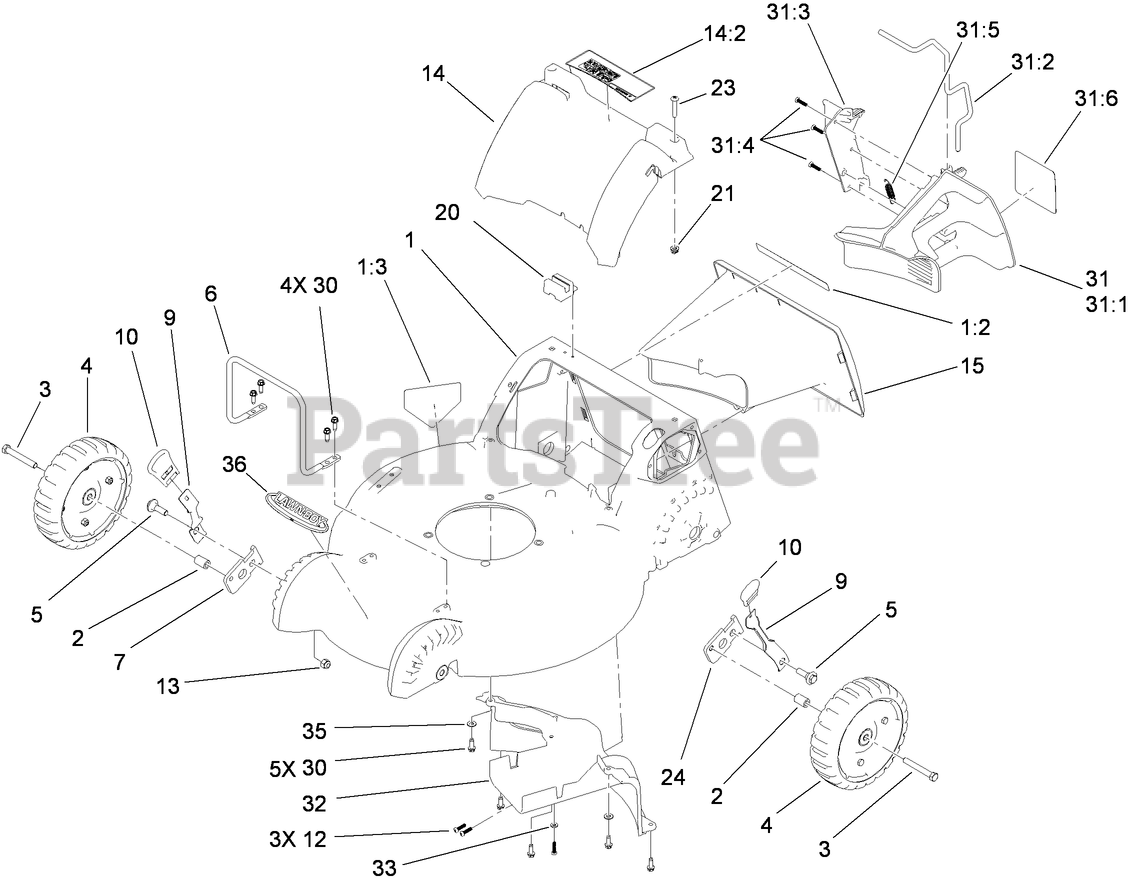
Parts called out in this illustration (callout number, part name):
1	Housing
1:2	DECAL-SAFETY
1:3	DECAL-DANGER
2	SPACER
3	SCREW-HH
4	8 INCH WHEEL ASM
5	SCREW-SHOULDER, HWH
6	GUARD-ENGINE
7	ARM-PIVOT, RH
9	ARM-SPRING, FRONT
10	Knob-Lever, HOC
12	SCREW-PLASTITE
13	NUT-LOCK, NI
14	COVER-REAR
14:2	DECAL-SAFETY
15	TUNNEL
20	MODULE-SWITCH
21	NUT-CLIP
23	SCREW-PTH
24	ARM-PIVOT, LH
30	SCREW-HWHTF
31	MULCH PLUG ASM
31:1	PLUG-MULCH, LH
31:2	LATCH-PLUG, MULCH
31:3	PLUG-MULCH, RH
31:4	SCREW-PLASTITE
31:5	SPRING-EXTENSION
31:6	DECAL-PLUG, MULCH
32	BAFFLE-REAR
33	WASHER-FLAT
35	WASHER-FLAT
